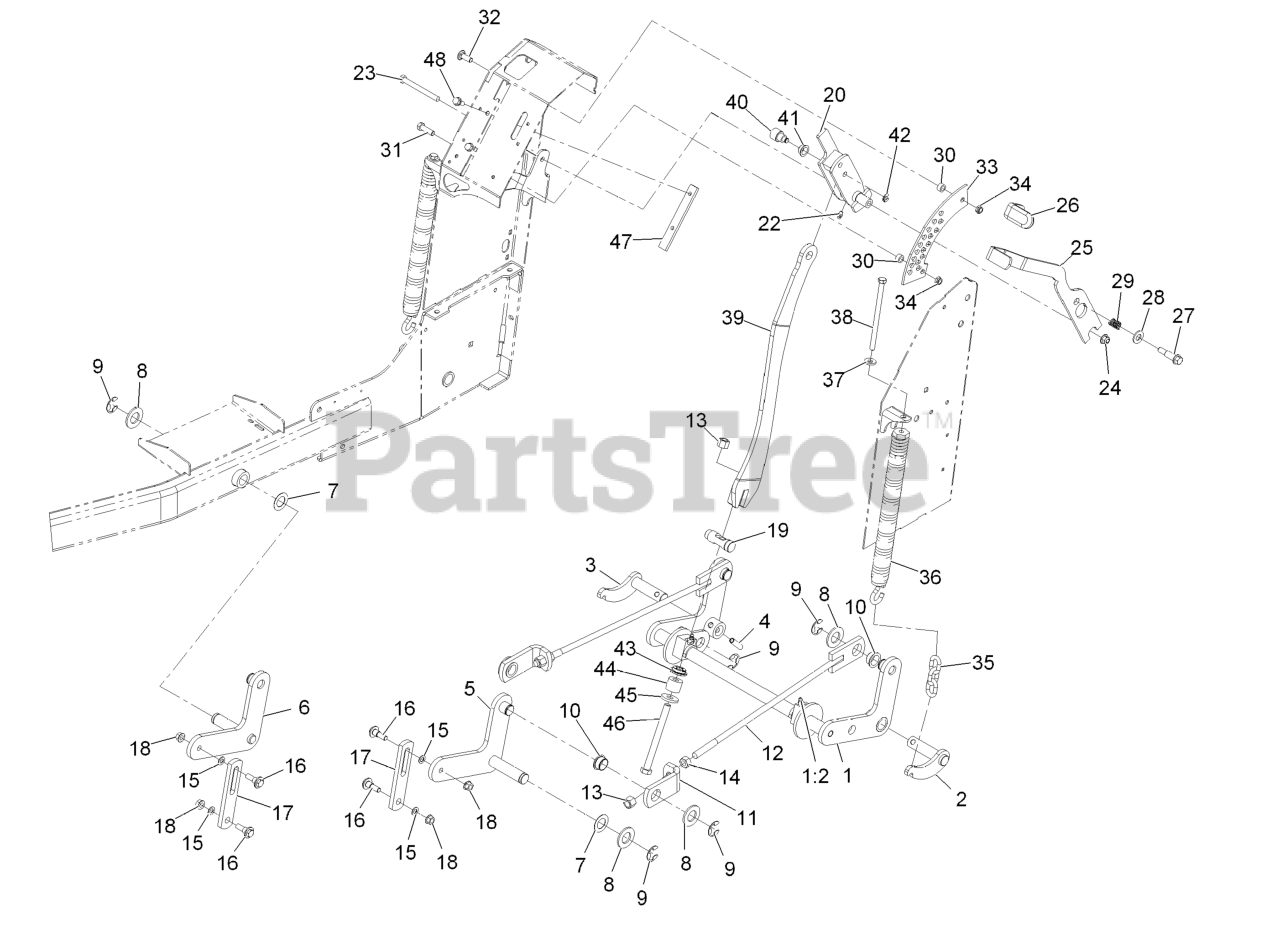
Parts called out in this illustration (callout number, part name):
1	REAR CROSSSHAFT ASM
1:2	FITTING-LUBE, 45 DEG
2	SHAFT-PIVOT, LH
3	SHAFT-PIVOT, RH
4	PIN-SPIRAL
7	WASHER-THRUST
8	WASHER-FLAT
9	RING-RETAINING, EXT
10	BEARING-FLANGE
11	BRACKET-LIFT ROD
12	LIFT ROD ASM
13	NUT-LOCK, NI
14	NUT-HH
16	SCREW-SHOULDER, HHF
17	LINK-LIFT
19	PIN-HOC
20	HOC HANDLE ASM
22	FITTING-GREASE
23	SCREW-HH
24	NUT-HF, NI
25	LEVER-HOC
26	GRIP-LEVER
27	SCREW-SHOULDER
28	WASHER-FLAT
30	SPACER
31	SCREW-HH
32	SCREW-CARR
33	BRACKET-HOC
35	CHAIN-DECKLIFT
36	SPRING-EXTENSION
37	WASHER-BELLEVILLE
38	BOLT-TAP, HH
39	BAR-LIFT
40	HUB-PIVOT
41	BEARING-FLANGE
42	RING-RETAINING
43	SEAT-SPRING
44	SPRING-URETHANE
46	SCREW-HH
47	SKID-HANDLE, LIFT
48	SCREW-THD ROLL, HWH
